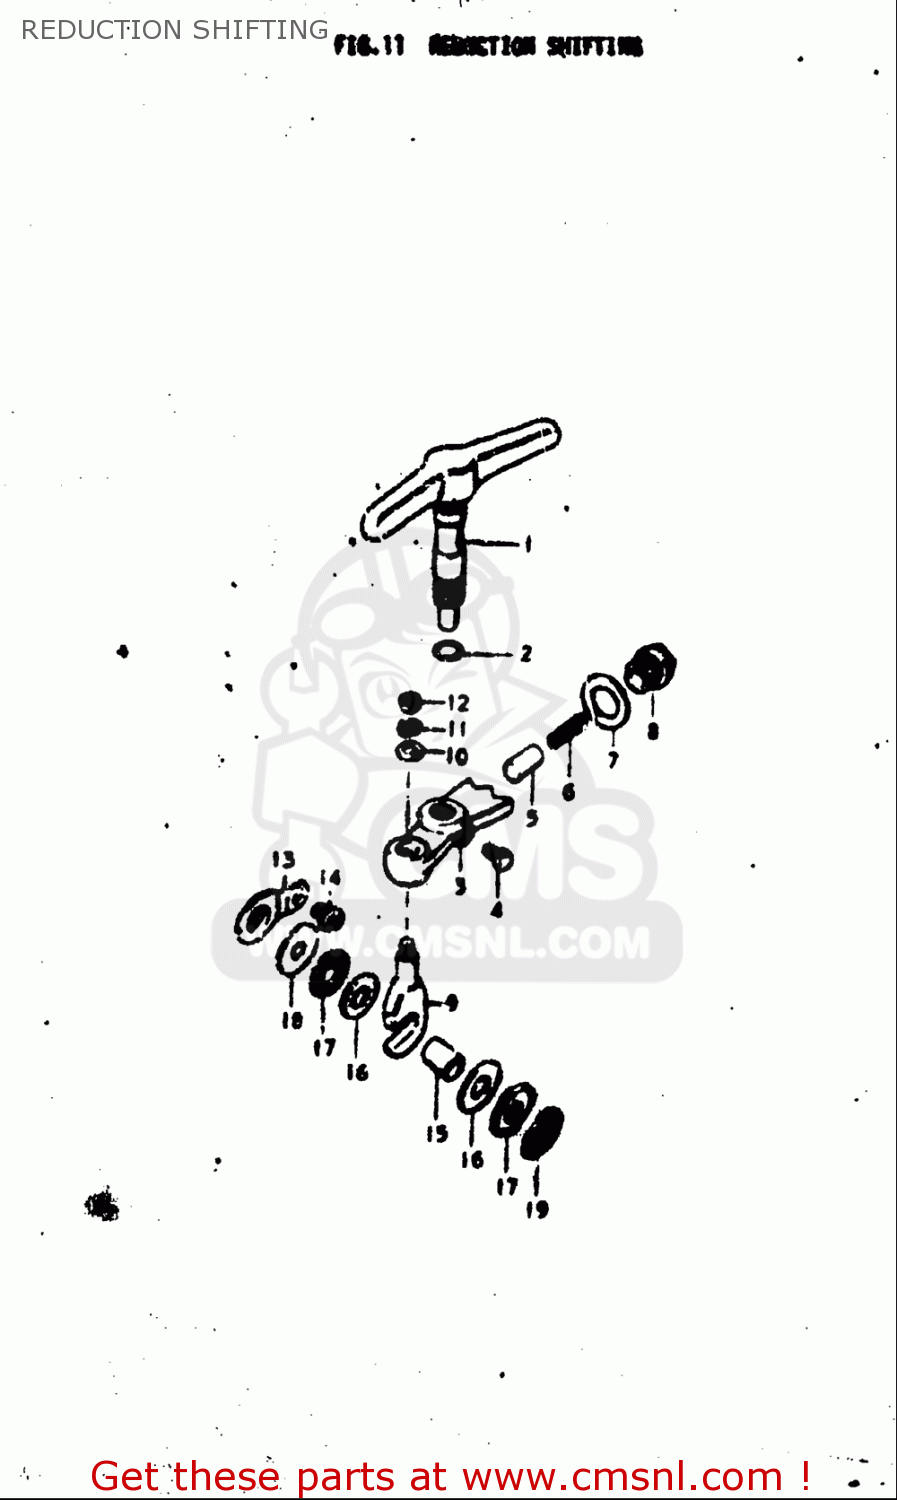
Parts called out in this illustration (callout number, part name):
2	O RING(D:1.3,ID:9.6)
5	STOPPER,GEAR SHIFTING
6	SPRING
10	WASHER
11	WASHER,LOCK
14	SCREW
15	SPACER(6X10X12.2)
16	WASHER(10.5X18X1)
17	BEARING(10X22X2.8)
18	WASHER
19	WASHER (6X22X2)
